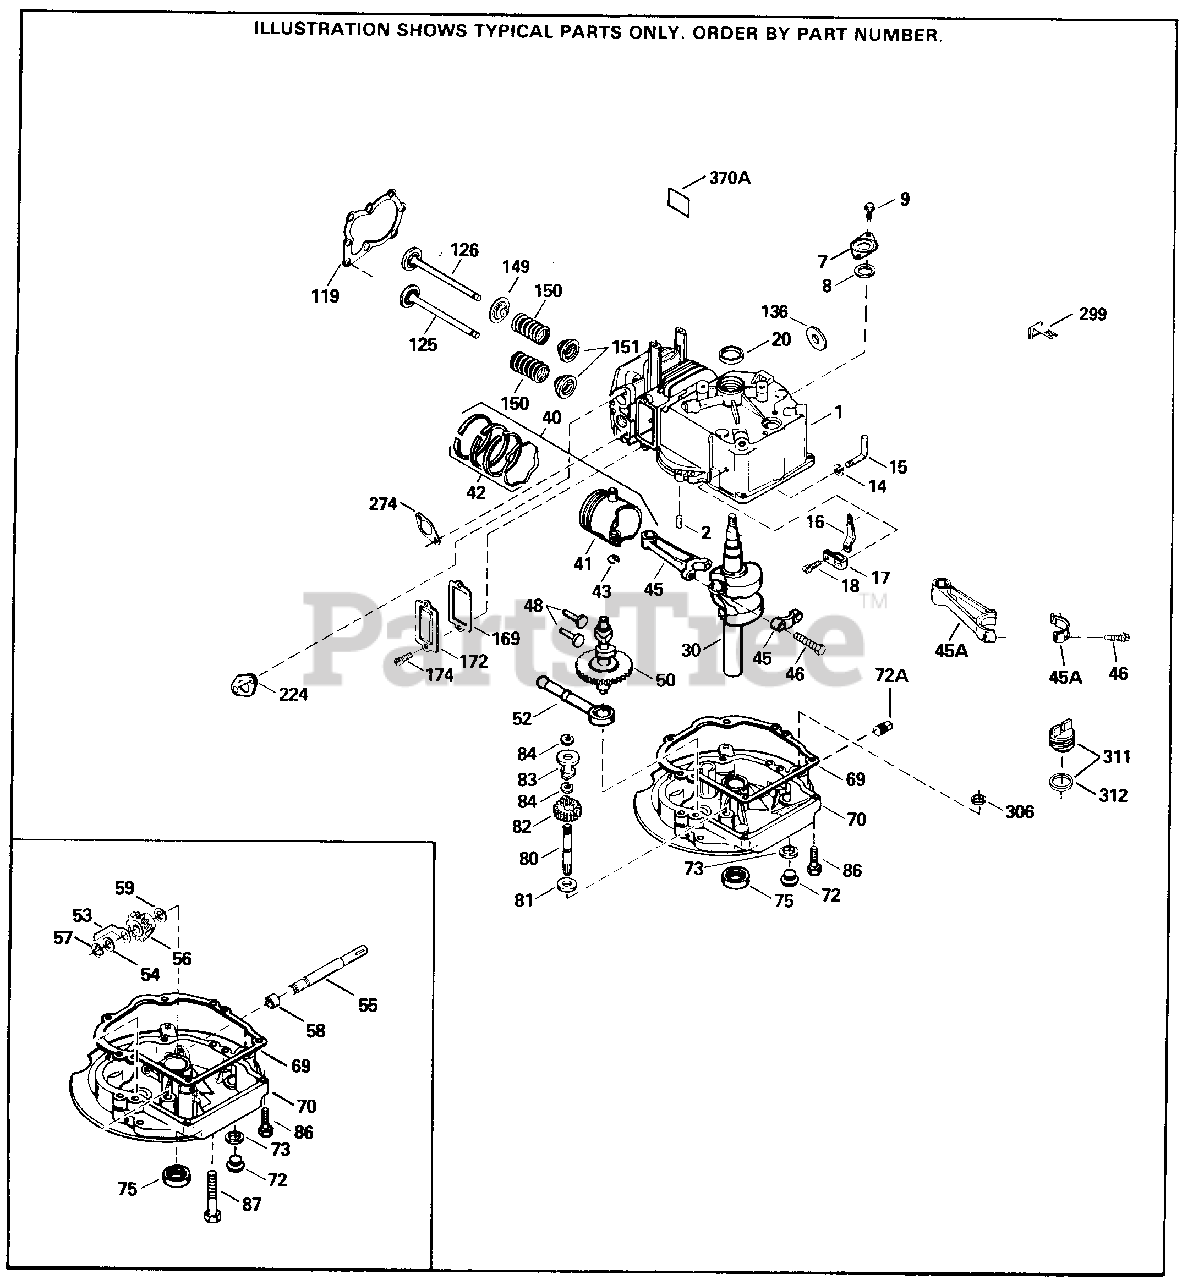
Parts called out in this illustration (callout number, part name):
1	"Cylinder (Incl. 2, 20 & 136) 2-5/8" B ore
2	Dowel Pin
8	Breather Gasket
14	Flat Washer
15	Governor Rod
17	Governor Lever Clamp
20	Oil Seal
30	Crankshaft
40	Piston, Pin & Ring Set (.020" OS) (In cl. 41, 42 & 43)
40	Piston, Pin & Ring Set (Std.) 2-5/8"
40	Piston, Pin & Ring Set (.010" OS)
41	Piston & Pin Assembly (Std.) (Incl. 4 3) 2-5/8")
41	Piston & Pin Assembly (.010" OS) (Inc l. 43)
41	Piston & Pin Assembly (.020" OS) (Inc l. 43)
42	Ring Set (Std.) (2-5/8" Bore)
42	Ring Set (.010" OS)
42	Ring Set (.020" OS)
43	Piston Pin Retaining Ring
45A	Connecting Rod Ass'y. (Incl. 46)
46	Connecting Rod Bolt
48	Valve Lifter
50	Camshaft (MCR
52	Oil Pump Ass'y.
53	Tang Washer
54	Flat Washer
55	P.T.O. Shaft
56	Left Hand Worm Gear (Helix)
57	Retaining Ring
58	Oil Seal
59	Flat Washer
69	Mounting Flange Gasket
70	Mounting Flange (Incl. 72, 75 & 80)
72	Oil Drain Plug (Incl. 73)
75	Oil Seal
80	Mechanical Governor Shaft
81	Flat Washer
82	Governor Gear Ass'y. (Incl. 81)
83	Governor Spool
84	Retaining Ring
86	Screw, 1/4-20 x 1-1/4"
87	Screw, 1/4-20 x 2-1/4"
119	Cylinder Head Gasket
125	Exhaust Valve (Std.) (Incl. 151)
125	Intake Valve (Std.) (Incl. 151)
125	Exhaust Valve (1/32" OS) (Incl. 151)
126	Exhaust Valve (1/32" OS) (Incl. 151)
136	S.E. Brake Washer
150	Valve Spring
151	Lower Valve Spring Cap
169	Valve Cover Gasket
169	Breather, Gasket
172	Valve Spring Box Cover
174	Screw, 1/4-20 x 1/2"
224	Intake Pipe Gasket
274	Intake Pipe Gasket
299	Wire Clip
306	"O" Ring This "O" ring is required wi th metal fill tube only when replacem ent mounting flange with .777 dia. oi l fill hole has been used.
311	Oil Fill Plug (Incl. 312) also availa ble in Packaged Part #740079
312	Oil Fill Plug Gasket
370A	Lubrication Decal
